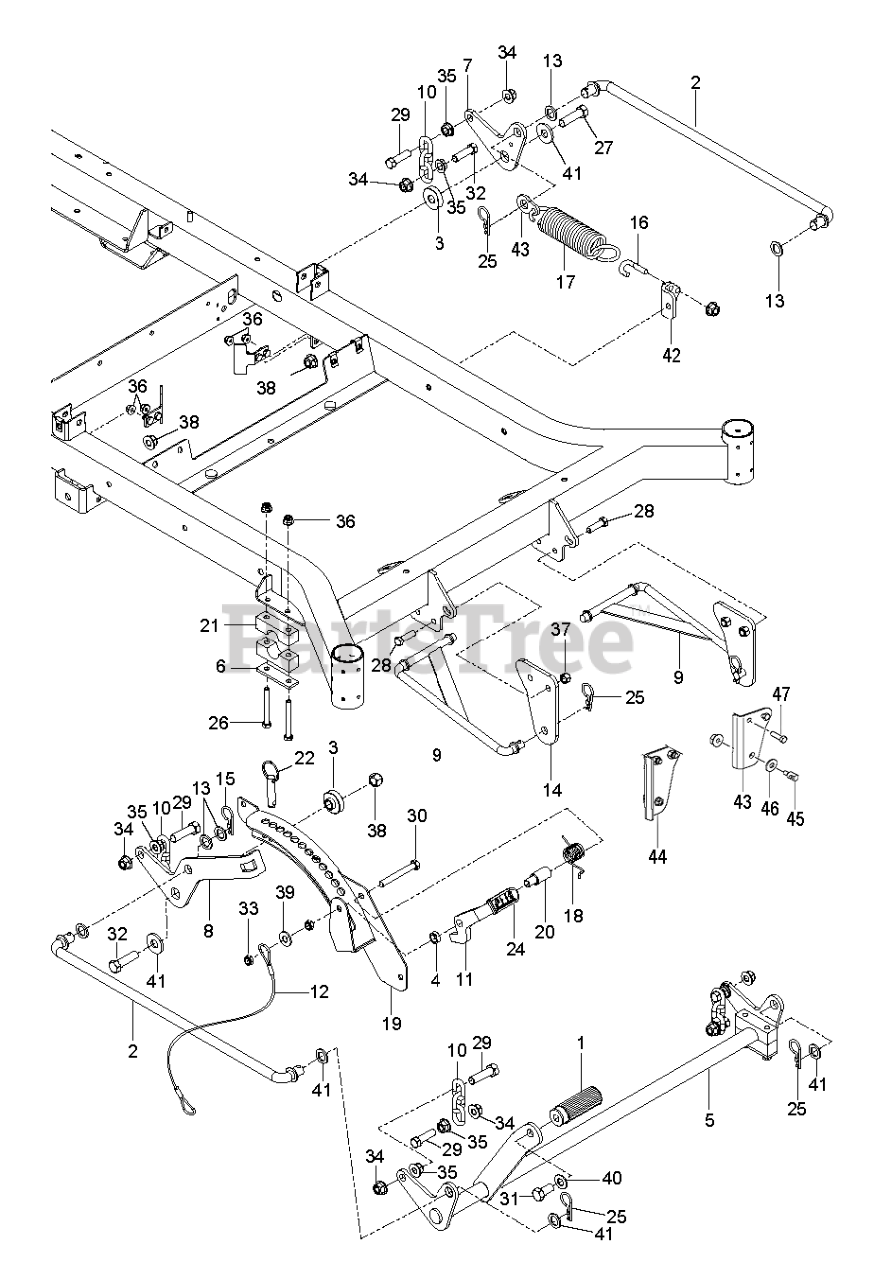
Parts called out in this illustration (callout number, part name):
1	PEDAL, DECK HEIGHT
2	CROSS LINK
3	SPACER.IDLER.METAL.POWDER
3	IDLER SPACER
4	SPACER, .3
5	LIFT.PNT.MZ.DECK.WELD.E-DIP
6	REINFORCEMENT.PLATEX431
7	BELLCRANK, RR, LIFT
8	BELLCRANK, RR, RT
8	BELLCRANK REAR.RT BLACK X431
9	STRUT LINKAGE
10	LIFT CHAIN - 3 LINK
11	LATCH, TRANSPORT
13	BUSHING
13	WASHER LT
14	MOUNT, STRUT
15	PIN.COTTER.7/16.BOW TI.
17	SPRING
18	SPRING, TORSION
19	HEIGHT, ADJUST, DECK
20	PIVOT, LATCH, TRANSPORT
21	PILLOW BLOCK
22	PIN, 1/2 X 1 1/2, DETENT RING
24	GRIP, TRANSPORT-RELEASE
25	PIN, COTTER 1 3/4
25	PIN.COTTER.7/16.BOW TI.
26	HCS 5/16C X 2-3/4
26	BOLT HEX
27	HCS 1/2-13 X 1 3/4 GR 8
28	HCS 3/8C X 1 1/4 GR5
29	HCS 7/16C X 1 1/2
30	BOLT.HEX.FIN.3/8-16 X 3.GR5
30	HCS 3/8C X 3
31	HHCS 1/2-13 X 1
32	HCS 7/16 - 14 X 1 3/4
33	NUT HEX 3/8-16 NYLON, THIN
34	NUT 7/16-14 HEX WHIZ LK
34	NUT 1/2-13 HEX NYLOC ZD
35	NUT 7/16C WHIZ
35	HHFS 3/8-16 X 2 3/4
36	5/16-18 NYLOC FLANGE NUT
37	NUT 3/8-16 NYLOC
38	NUT.LK.W/WSH.1/2.
38	NUT 7/16C WHIZ
39	RP WASHER 3/8 FLAT
40	CONTACT BELLSPR 1/2
40	WASHER, 7/16 DISC SPRING
41	WASHER.9/16 X 1 3/8 X 12 GA.
41	WASH USS FLAT 1/2
43	BRACKET.PNT.SUSP.CHAS.FR.LH.OR
44	BRACKET.PNT.SUSP.CHAS.FR.RH.OR
45	STUD.FASTNER.W/ANTI-ROTATE
46	WASHER.CLEAR.ZINC
47	HCS 3/8-16X1.GRD.5.ZD
